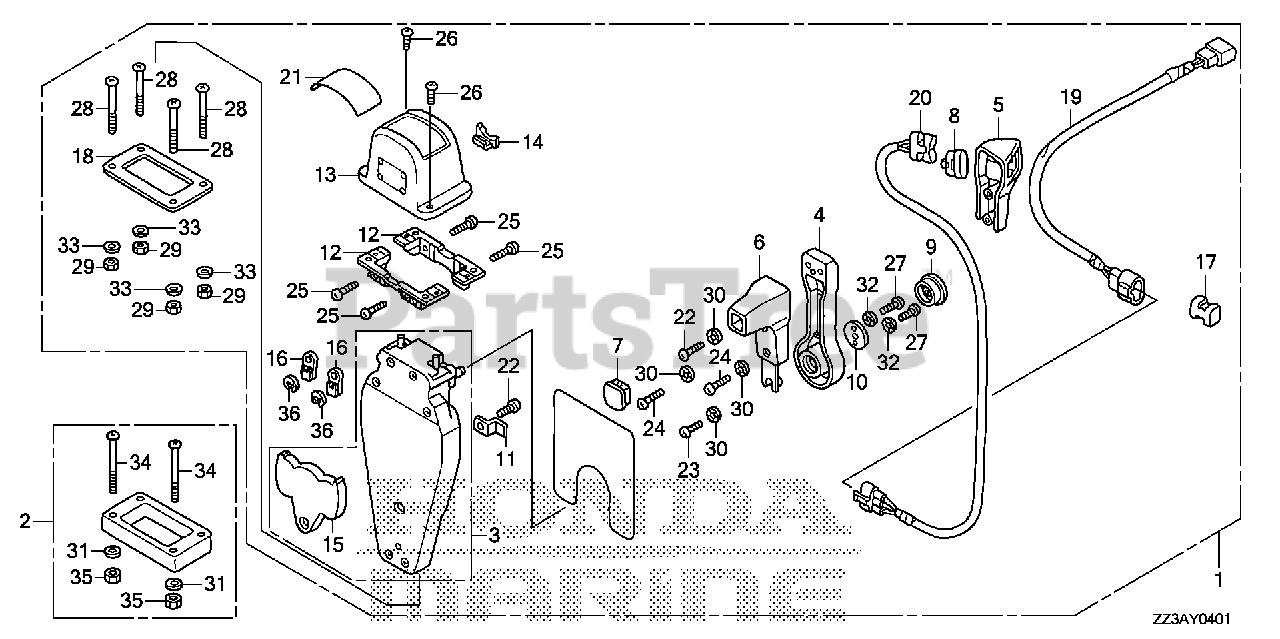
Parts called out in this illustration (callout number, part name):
1	BOX KIT, REMOTE CONTROL (TOP MOUNT SINGLE)(L)
2	SPACER KIT, REMOTE CONTROL BOX (TOP MOUNT SINGLE)
3	HOUSING ASSY., R. (INNER) (TOP MOUNT)
4	HANDLE, REMOTE CONTROL
5	COVER, R. GRIP
6	GRIP, REMOTE CONTROL HANDLE
7	CAP, GRIP
8	CAP, SWITCH
9	BUTTON, THROTTLE
10	PLATE, HANDLE
11	PLATE, CABLE CLAMP
12	BRACKET, REMOTE CONTROL HOUSING
13	HOUSING, REMOTE CONTROL BOX
14	HOUSING, LEAD
15	PLATE, DWELL
16	TERMINAL, CABLE
17	SPACER, CABLE CLAMP
18	GASKET, SINGLE
19	SUB-HARNESS ASSY., POWER TRIM-TILT (B)
20	SWITCH ASSY., POWER TRIM-TILT (B)
21	MARK, REMOTE CONTROL (SINGLE)
22	SCREW, PAN (5X16)
23	SCREW, PAN (5X10)
24	SCREW, PAN (5X20)
25	SCREW, PAN (5X18)
26	SCREW, PAN (4X10)
27	SCREW, PAN (6X18)
28	SCREW, PAN (5X40)
29	NUT, HEX. (5MM)
30	WASHER, LOCK (5MM)
31	WASHER, PLAIN (5MM)
32	WASHER, LOCK (6MM)
33	WASHER, PLAIN (5MM)
34	SCREW, PAN (5X65)
35	NUT, HEX. (5MM)
36	E-RING (6MM)
